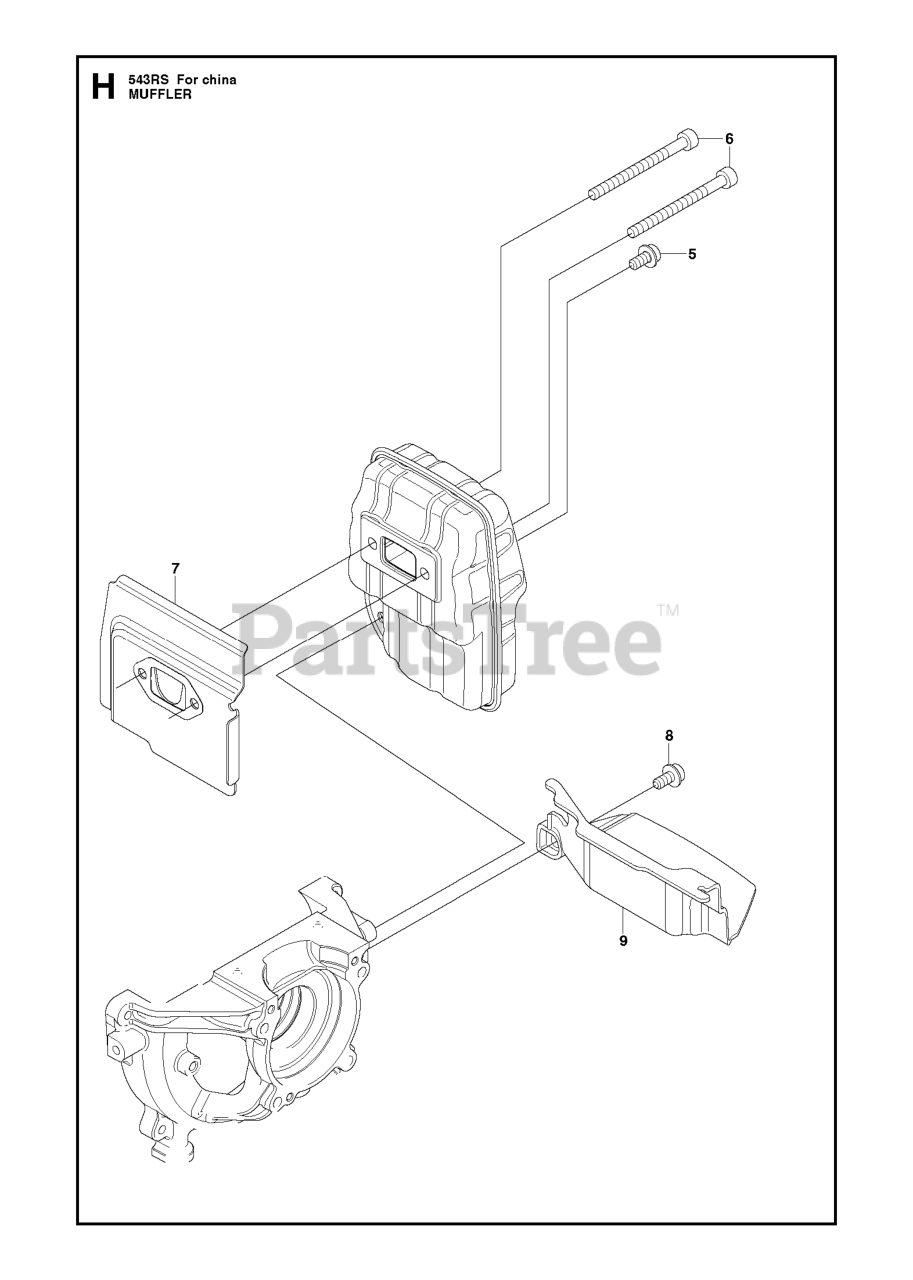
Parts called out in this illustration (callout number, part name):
5	BOLT (RPLS T495051010-11)
6	BOLT
8	BOLT (RPLS T495051010-11)
